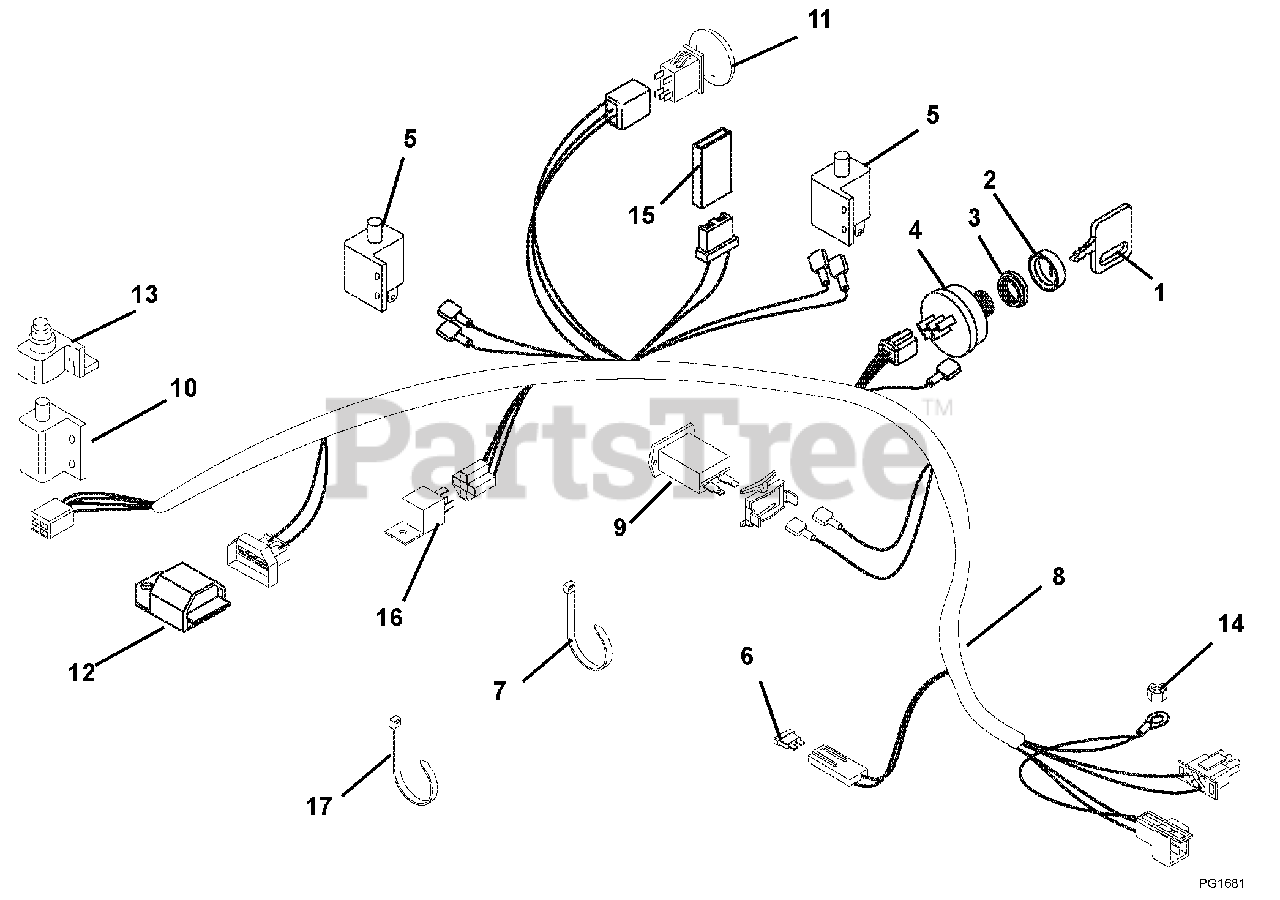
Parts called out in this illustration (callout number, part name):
1	Key- with Cap
2	Cap, Ignition Switch
3	Nut, Panel .562-24
4	Key Switch
5	Switch- Double Pole N.O./N.O.
6	Fuse-25 AMP
7	Tie Wrap-Black
8	Wire Harness-Hydro Recoil-Pro Steer
9	Hour Meter-Quartz
10	Switch, Interlock
11	Switch- PTO- NMIR
12	Module, Interlock Recoil
13	Boot, Rubber
14	Nut-Locking-Top-Flange .31-18
15	Diode, Connector Shell
16	Relay
17	Tie Wrap
